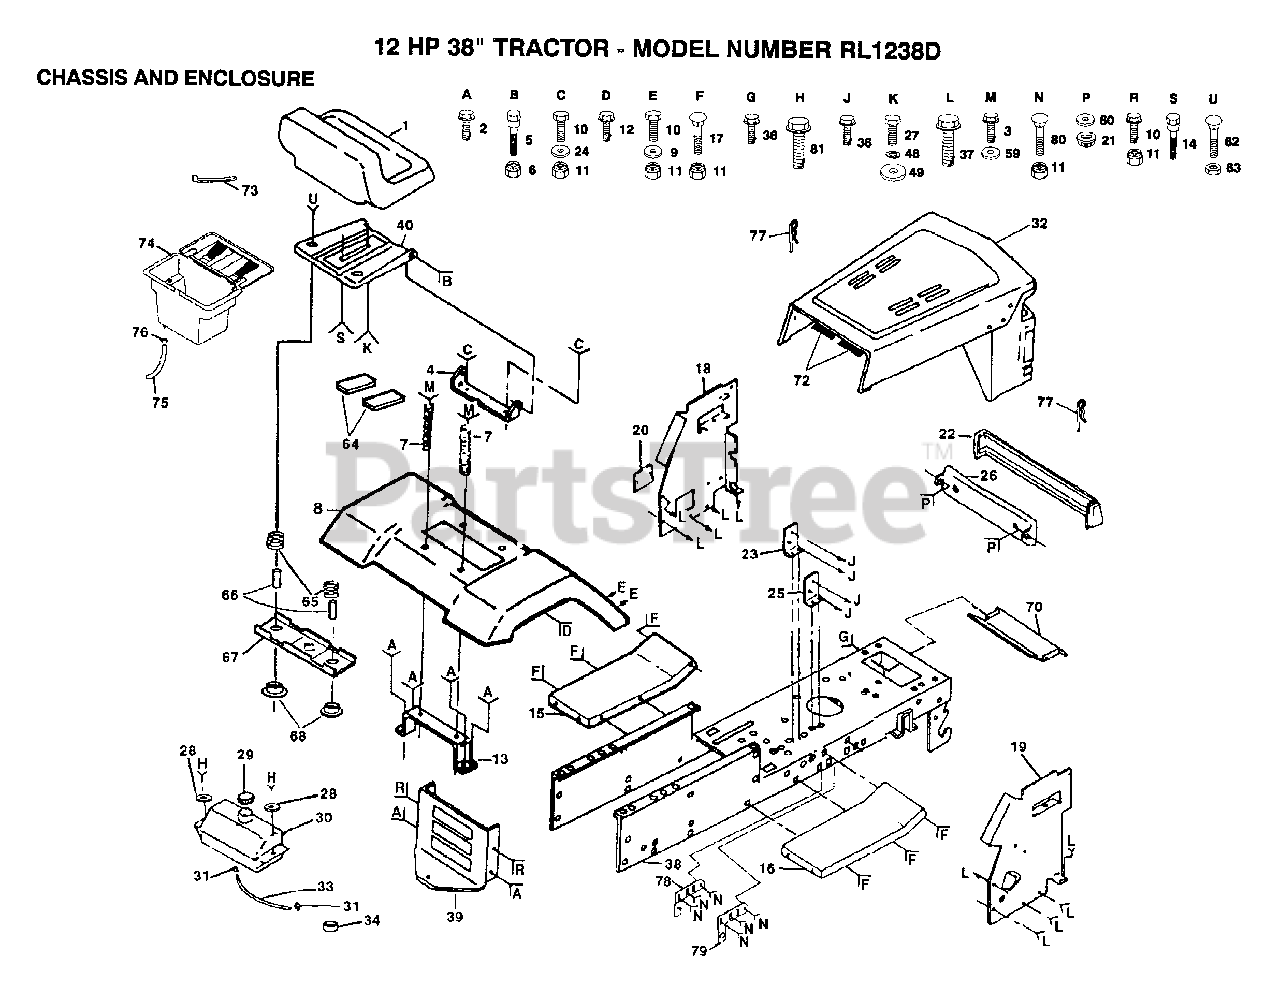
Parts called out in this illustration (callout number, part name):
2	SCREW
3	SCREW GTV
7	SPRING COMPRESSIO
9	WASHER
12	SCREW LT
14	"BOLT,SHOULDER"
15	FOOTREST LH
16	FOOTREST
17	BOLT
18	DASH PANEL LH
20	COVER ACCESS
21	PAL NUT LT
23	SWITCH BRACKET
24	WASHER
25	BRACKET LT
27	BOLT
28	WASHER
30	TANK.FUEL.LT.
31	HOSE CLAMP
32	HOOD/GRILL ASM
33	FUEL LINE T
35	SCREW
36	SCREW
37	SCREW LT
39	DRAWBAR LT/YT
48	LOCKWASHER
49	WASHER
59	WASHER
60	WASHER PM
64	STRIP FORM
65	SPRING
66	SPACER SPLIT
67	BRKT SWITCH
68	BUSHING
70	HEAT SHIELD
73	WIRE TIE
76	HOSE CLAMP T
77	SPRING.RETAINER
78	BRKT ASM PIVOT LH
79	BRKT ASM PIVOT RH
80	BOLT
81	SCREW HEX CRT
